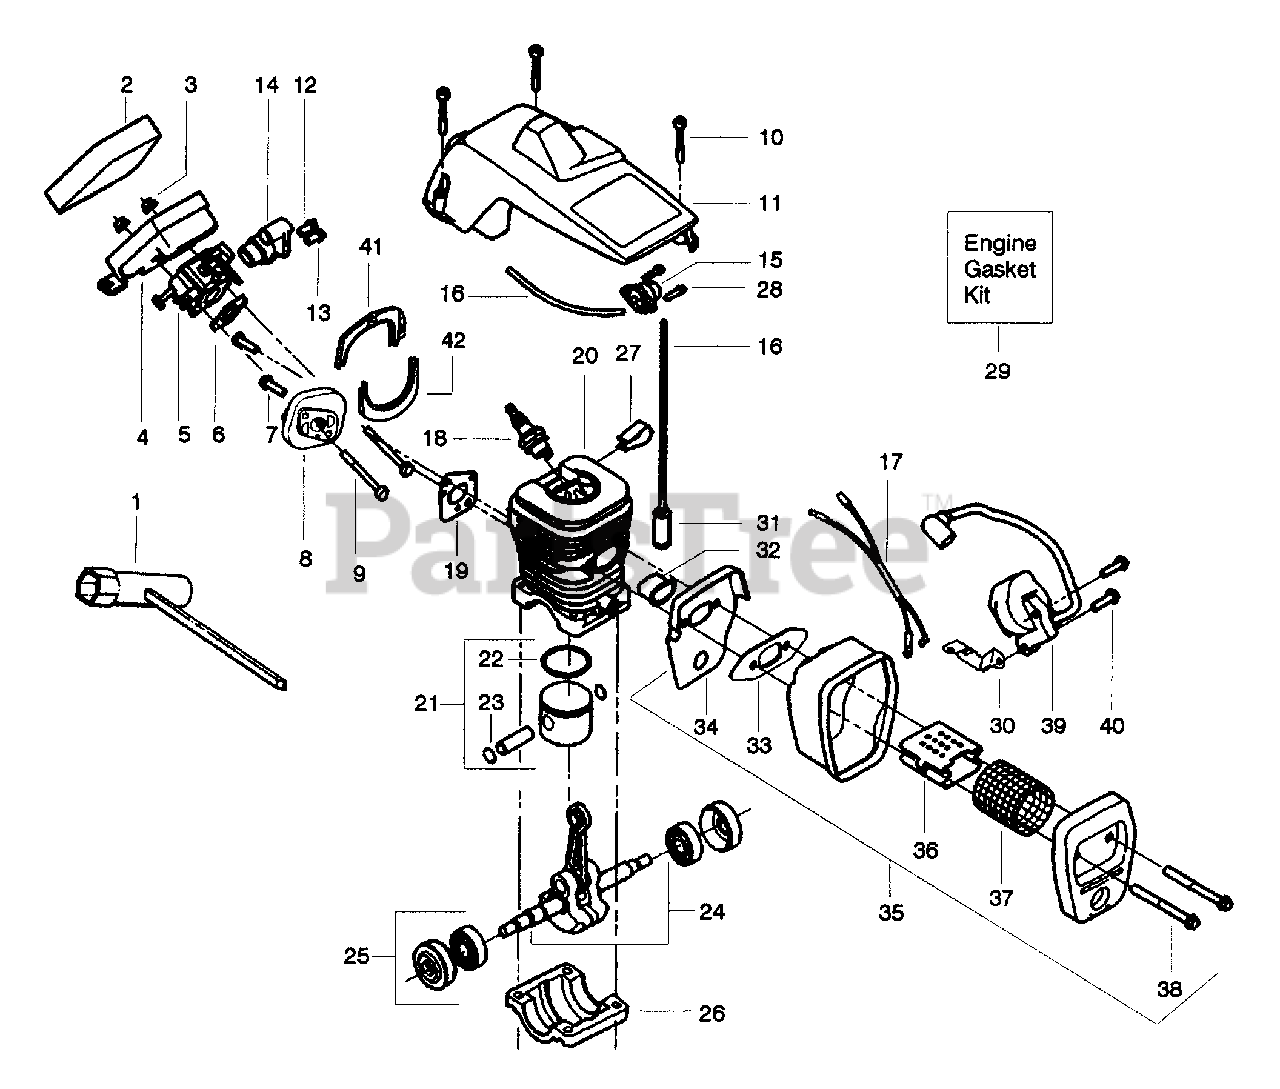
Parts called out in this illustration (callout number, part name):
1	Bar Wrench
2	Foam - Air Filter
4	Air Filter Housing
5	Carburetor Kit
6	Carb. Gasket
7	Screw
8	Carb. Adapter
11	Cylinder Shield
12	Limiter Cap - High
13	Limiter Cap - Low
14	Grommet - Carb Adjust
15	Air Purge Ass'y.
16	Fuel Line Kit (Small)
17	Wire Harness Ass'y.
18	Spark Plug (CJ-7Y)
19	Gasket - Carb Adaptor
20	Cylinder Kit
21	Piston Kit
22	Piston Ring
23	Retainer - Piston Pin
24	Crankshaft Ass'y.
25	Seal & Bearing Ass'y.
26	Cap - Crankcase
27	Clip - High Tension Lead
29	Engine Gasket Kit
30	Ground Strap
31	Fuel Pick - up Ass'y.
32	Heat Insulator
33	Muffler Gasket
34	Muffler Backplate
35	Muffler Ass'y.
36	Muffler Diffuser
37	Spark Screen
39	Ignition Module
41	Seal - Carb Adapter - (Upper)
42	Seal - Carb Adapter - (Lower)
